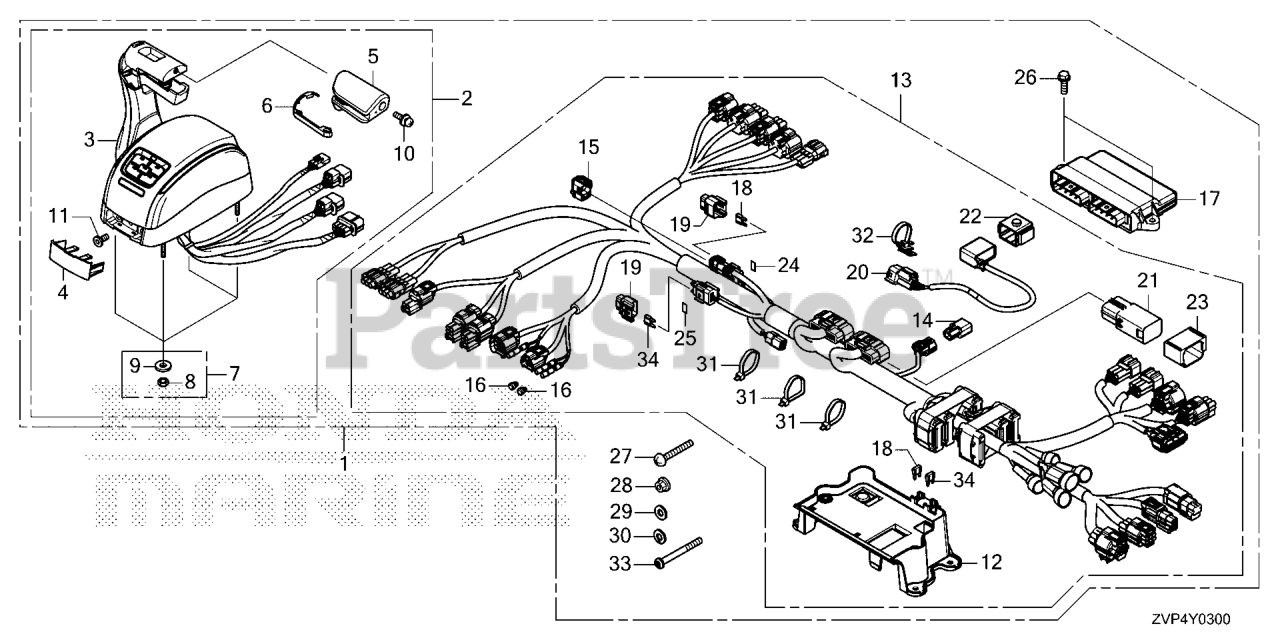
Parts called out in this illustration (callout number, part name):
1	BOX KIT, R/C
2	BOX ASSY., REMOTE CONTROL (TOP MOUNT SINGLE)(RH)
3	CONTROL HEAD
4	COVER CAP
5	GRIP
6	GRIP PLATE
7	NUT SET, MOUNTING
8	NUT
9	WASHER
10	PAN HEAD SCREW
11	SOCKET HEAD CAP SCRE
12	CASE, CONTL UNIT
13	CASE ASSY,CONTL UNIT
14	TERMINATOR ASSY.
15	CAP, DUMMY (WPC 4P 090 M) (RED)
16	PLUG, CONNECTOR (INNER) (TROLLING CONTROL)
17	UNIT ASSY., CONTL
18	FUSE, BLADE (3A)
19	COVER ASSY., FUSE
20	RELAY ASSY., CONTROL (NOT AVAILABLE)
21	RELAY ASSY., MAIN
22	HOLDER, RELAY (NOT AVAILABLE)
23	CUSHION, RELAY
24	LABEL, FUSE (3A)
25	LABEL, FUSE (5A)
26	BOLT, FLANGE (6X20)
27	SCREW, PAN (5X40) DUAL QTY = (8) (SINGLE)
28	NUT, FLANGE (5MM)
29	WASHER, PLAIN (5MM)
30	WASHER, SPG (5MM)
31	BAND, SELF-LOCK Use from Frame SN 3000253.
32	HOLDER, CONNECTOR (128.6MM) (NATURAL)
33	SCREW, PAN (5X65)
34	FUSE, MINI (5A)
